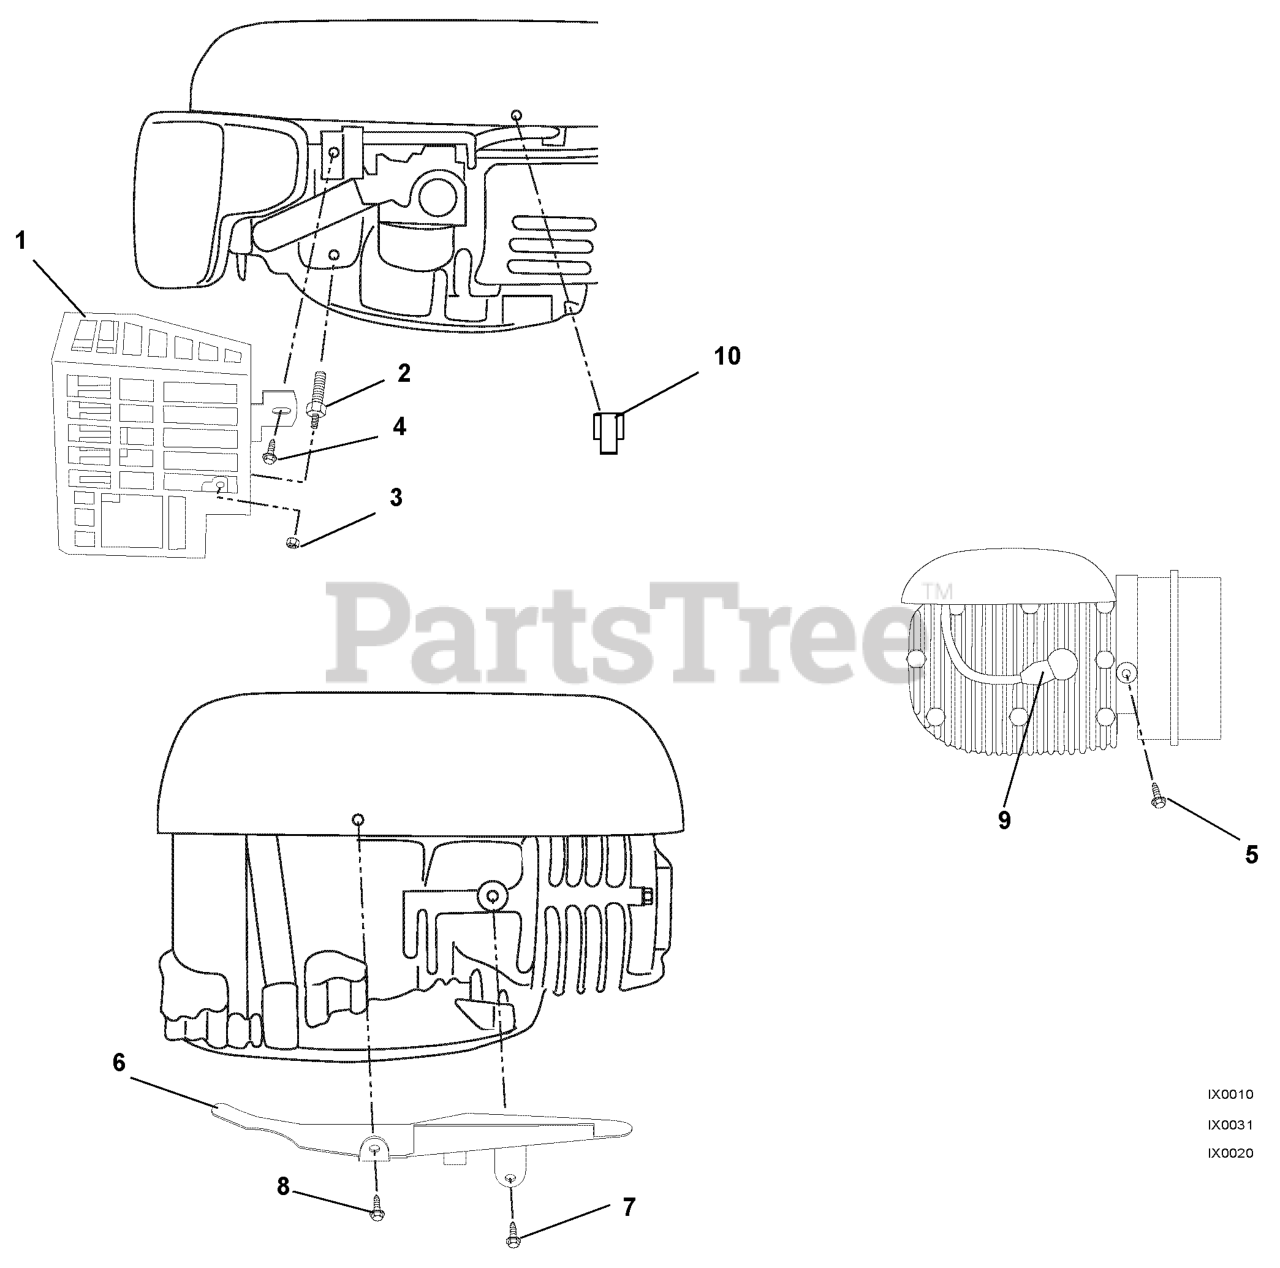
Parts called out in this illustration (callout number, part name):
1	GUARD-MUFFLER-STRING TRIM CE
2	SCR-SPECIAL .25-20X1/10-24X.31
3	@NUT-LK-NYL 10-24 W/INSRT YWZC
4	@SCR-TAP 10-24X.50 HWH TR YWZC
5	@SCR-TAP .25-20X.50 HWH TR YWZ
6	GUARD-FLYWHEEL-LARGE STRTRM CE
7	@SCR-TAP .25-20X.37 HWH YWZ TR
8	SCR-TAP 8-15X.38 CR RH A YWZC
9	SHIELD, SPARK PLUG
10	CLIP, FINGER GUARD
